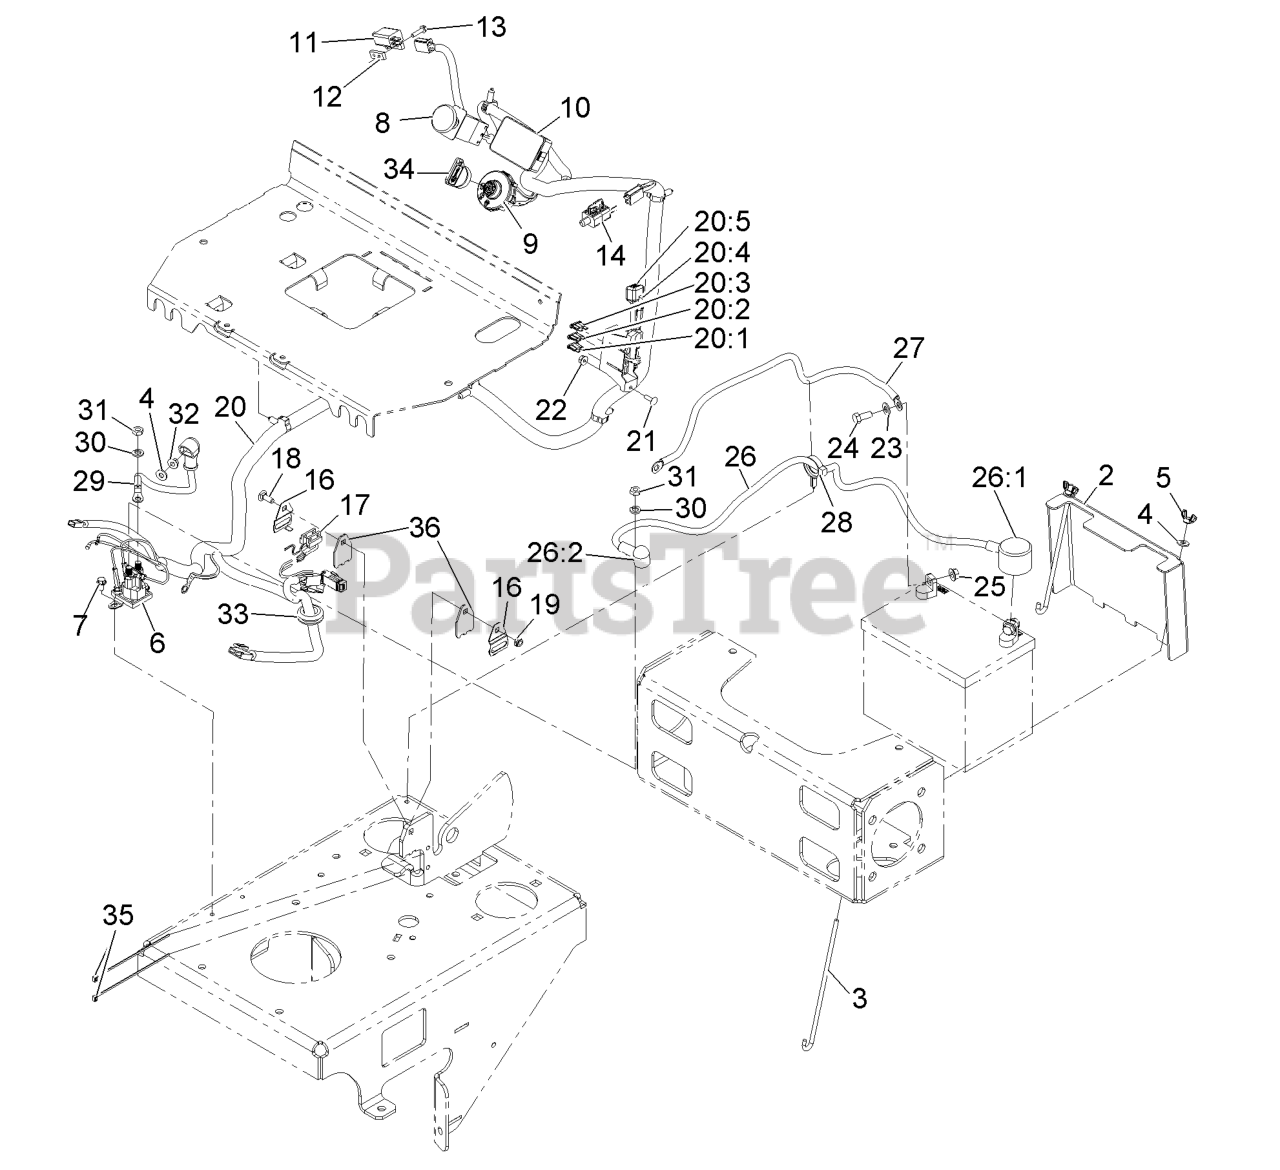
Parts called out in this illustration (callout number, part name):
2	COVER-BATTERY
3	BOLT-HOLDDOWN
4	WASHER-FLAT
5	WINGNUT
6	SOLENOID
7	SCREW-HWH
8	SWITCH-PTO, ON-ON
10	MODULE-HOUR METER
11	SWITCH-CLOSED, NORMALLY
12	PLATE-TAPPED
13	SCREW-HWH
14	SWITCH-PLUNGER, NC, SPST
16	CLAMP-SWITCH
17	HARNESS-SWITCH, REED
18	BOLT-CARR
19	NUT-LOCK, NI
20	HARNESS-WIRE
20:1	FUSE-BLADE, 30 AMP
20:2	FUSE-BLADE, 25 AMP
20:3	FUSE-BLADE, 10 AMP
20:4	CAP-PLUG
21	SCREW-CARR
23	WASHER-PLAIN
24	SCREW-HH
25	NUT-HHF, SMOOTH
26	ASM,POSITIVE BATTERY CABL
26:1	INSULATOR-BATTERY
26:2	INSULATOR-SOLENOID
27	CABLE-BATTERY, NEGATIVE
28	CLAMP-HOSE
29	CABLE-BATTERY, RED
30	WASHER-LOCK
31	NUT-JAM
33	GROMMET
34	KEY-IGNITION
35	TIE-CABLE
36	PLATE-SPACER
